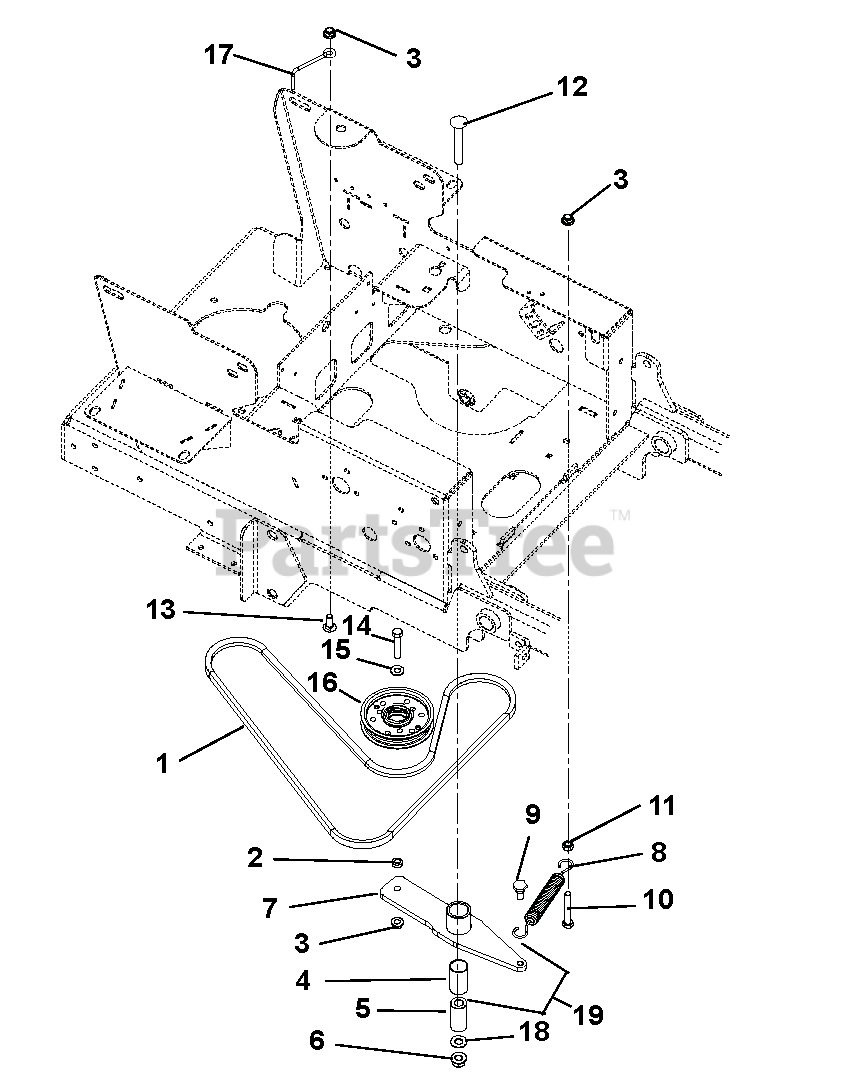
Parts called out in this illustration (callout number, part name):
1	V-BELT, 4L-WRAPPED
2	BSHG-SLV .377X.624X.235
3	@NUT-LK-NYL-FLG .38-16 YWZC
4	BSHG, 1.00 X 1.125 X 1.937
5	BSHG, SPCR .502X.997X2.03 PM
6	@NUT-LK-NYL-FLG .50-13 YWZC
7	WMT-HYDRO DRIVE IDLER ARM
8	SPRING, EXTENSION
9	BLT,SHLDR EP .38-16X.30 HEX YZ
10	@BLT-HEX .38-16X2.50 GR5 YWZC
11	@NUT-HEX .38-16 YWZC
12	@BLT-HEX .50-13X3.25 GR5 YWZC
13	@BLT-RDHDSQNK .38-16X1.00 G5YZ
14	@BLT-HEX .38-16X2.00 GR5 YWZC
15	@WSHR-FL-STL.406X.812X.065 YWZ
16	IDLER-FLAT 4.00 X .38 NWHAMSHR
17	BELT FINGER
18	WSHR-FL-STL.511X1.441X.125 YWZ
19	ASM, IDLER PIVOT ARM (HYDRO)
